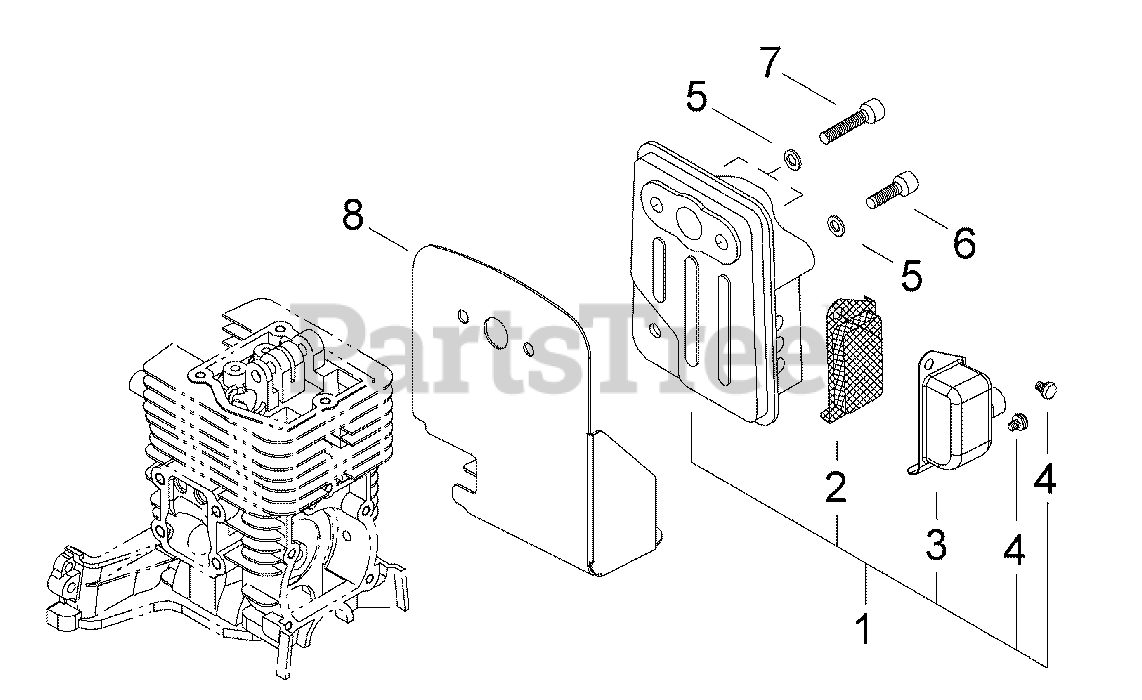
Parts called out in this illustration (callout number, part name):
1	MUFFLER ASSY
2	SCREEN, SPARK ARRESTER
3	GUIDE, EXHAUST
4	SCREW M4×6
5	WASHER, FLAT 5.5×10×0.8
6	BOLT 5×16
7	BOLT M5×25
8	HEAT SHIELD, EXHAUST
